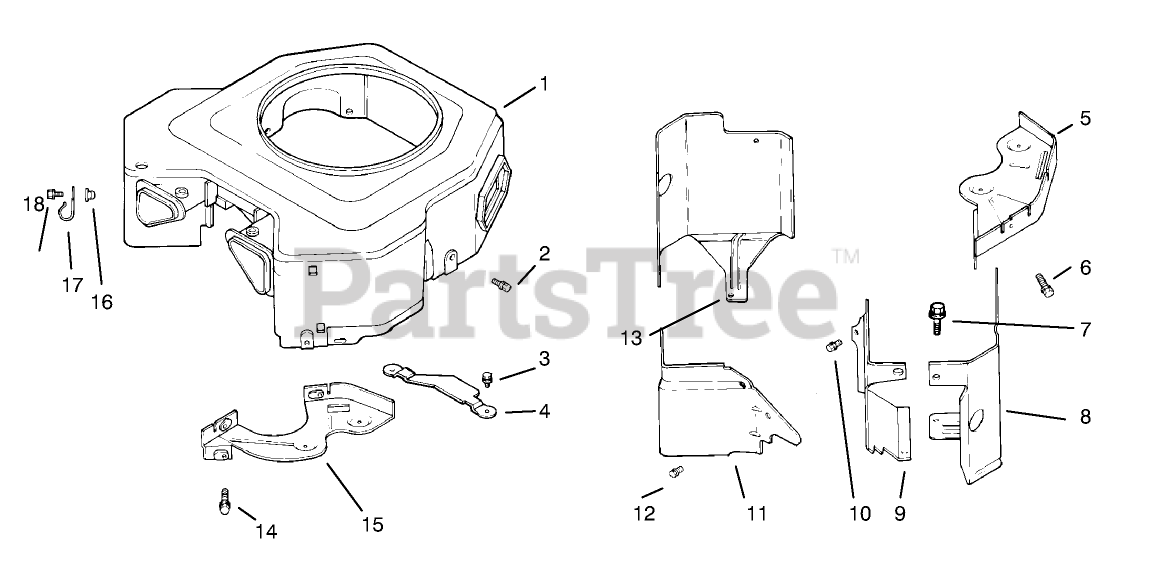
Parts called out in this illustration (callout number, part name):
1	Housing-Blower ASM (Only C)n: 72103, 72083)
4	Guard-Flywheel (Only On: 72103, 72083)
5	Plate-Backing #2 side
8	Baffle Cylinder #2 Side
9	Baffle-Valley #1 Side
11	Baffle-Valley #2 Side (Only On: 72103, 72083)
13	Baffle-Cyl. #1 Side
15	Plate-Backing #1
17	Clip-Cable (Only On: 72103)
